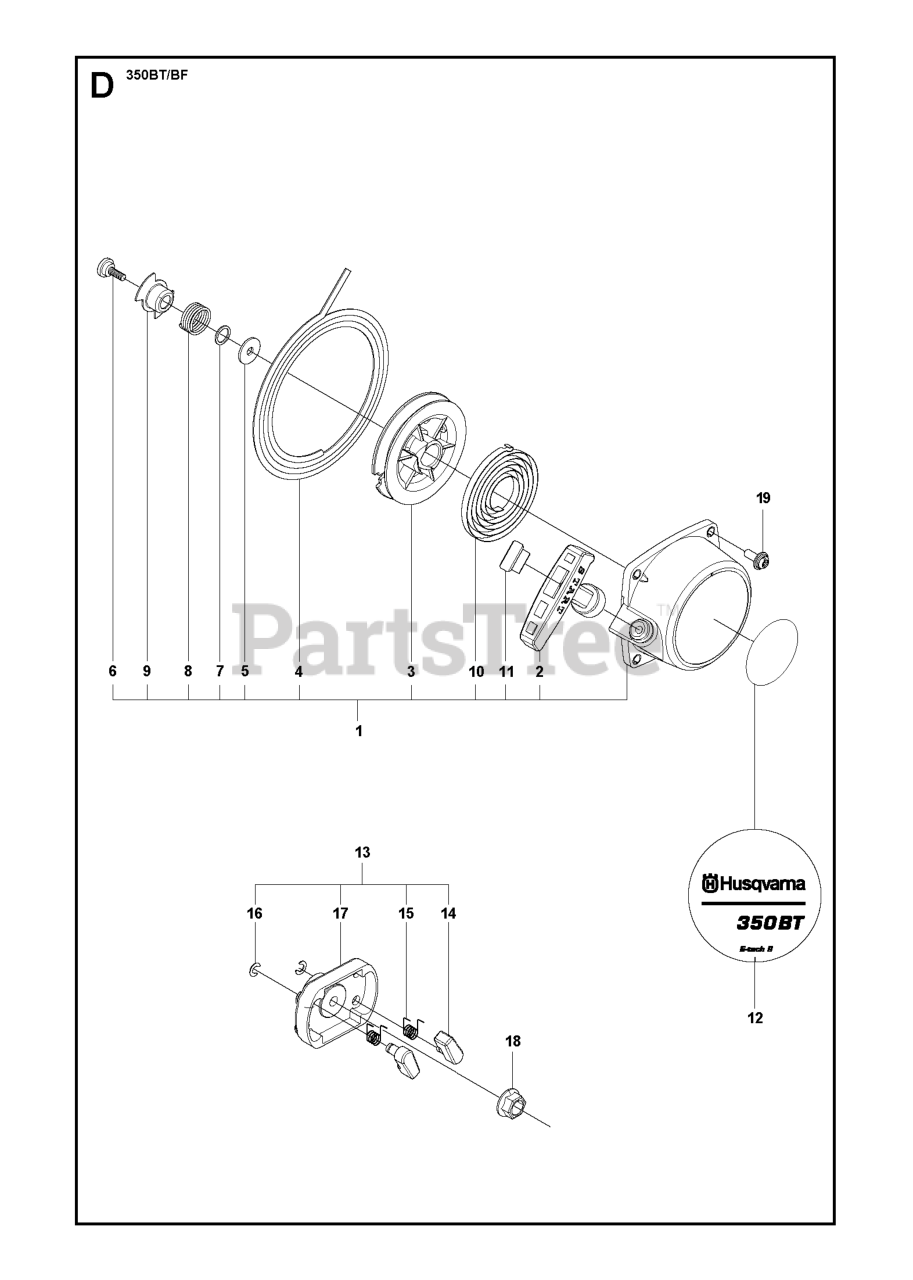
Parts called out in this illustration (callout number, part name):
1	STARTER ASSY
2	STARTER HANDLE
3	ROPE REEL
4	STARTER ROPE
5	WASHER
6	SCREW
7	WASHER
8	FRICTION SPRING
9	FRICTION PLATE
10	SPRING
11	STOPPER
12	LABEL, RECOIL 350BT
13	STARTER PULLEY ASSY
14	STARTER RATCHET
15	SPRING
16	CLIP
19	SCREW, T27
